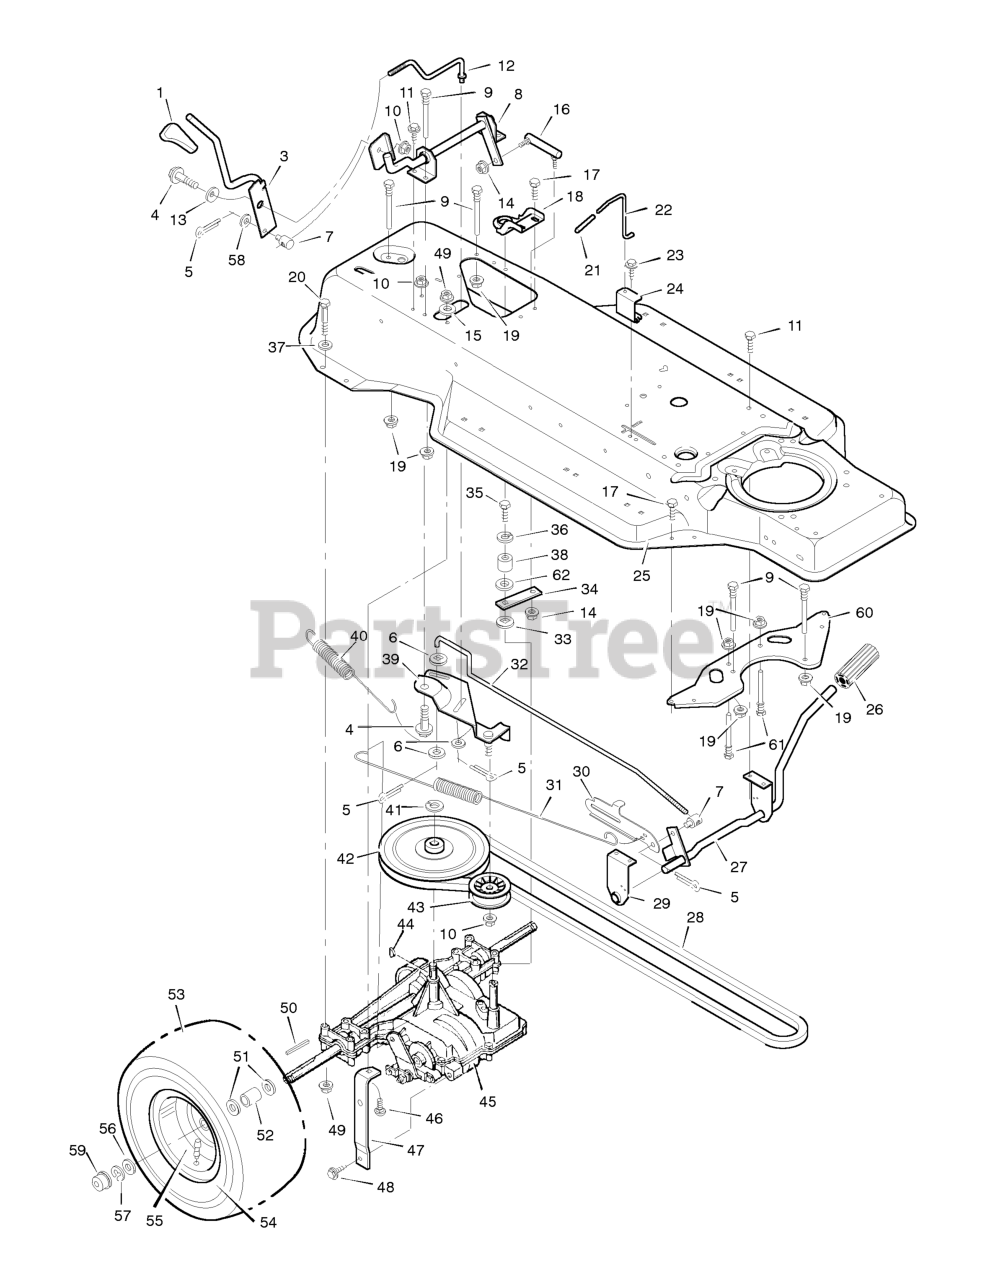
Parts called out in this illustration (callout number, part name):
1	Grip
3	Handle, Shift
4	Bolt, Shoulder
5	Pin, Cotter
6	Washer
7	Nut, Adjustable
8	Shifter Assembly
9	Guide, Belt
10	Locknut, Flange
12	Link, Clutch
13	Washer, Curved
14	Locknut, Flange
16	Link Assembly, Shifter
18	Bracket, Support
19	Nut, Flange
20	Bolt, Hex
22	Rod, Control
24	Guide, Bracket
25	Frame Assembly
26	Pedal, Clutch/Brake
27	Lever Assembly
28	Belt, Motion Drive
29	Bracket, Lever Support
30	Latch, Park Brake
31	Spring, Brake Extension
32	Rod, Clutch
34	Yoke, Shift
35	Bolt, Hex
36	Lockwasher
37	Washer
38	Pilot, Support
39	Bracket Assembly, Idler
40	Spring, Motion Drive
41	Ring, Retainer
42	Pulley, Motion Drive
43	Pulley, Backside Idler
44	Key, Woodruff
45	Transaxle, Peerless **
46	Bolt, Carriage
47	Support, Transaxle
49	Locknut, Flange
50	Key, Square
52	Spacer, Transaxle
53	Tire *
54	Wheel and Tire Assembly
55	Valve Stem
58	Washer
59	Hub Cap
60	Plate, Belt Guide
61	Guide, Belt
